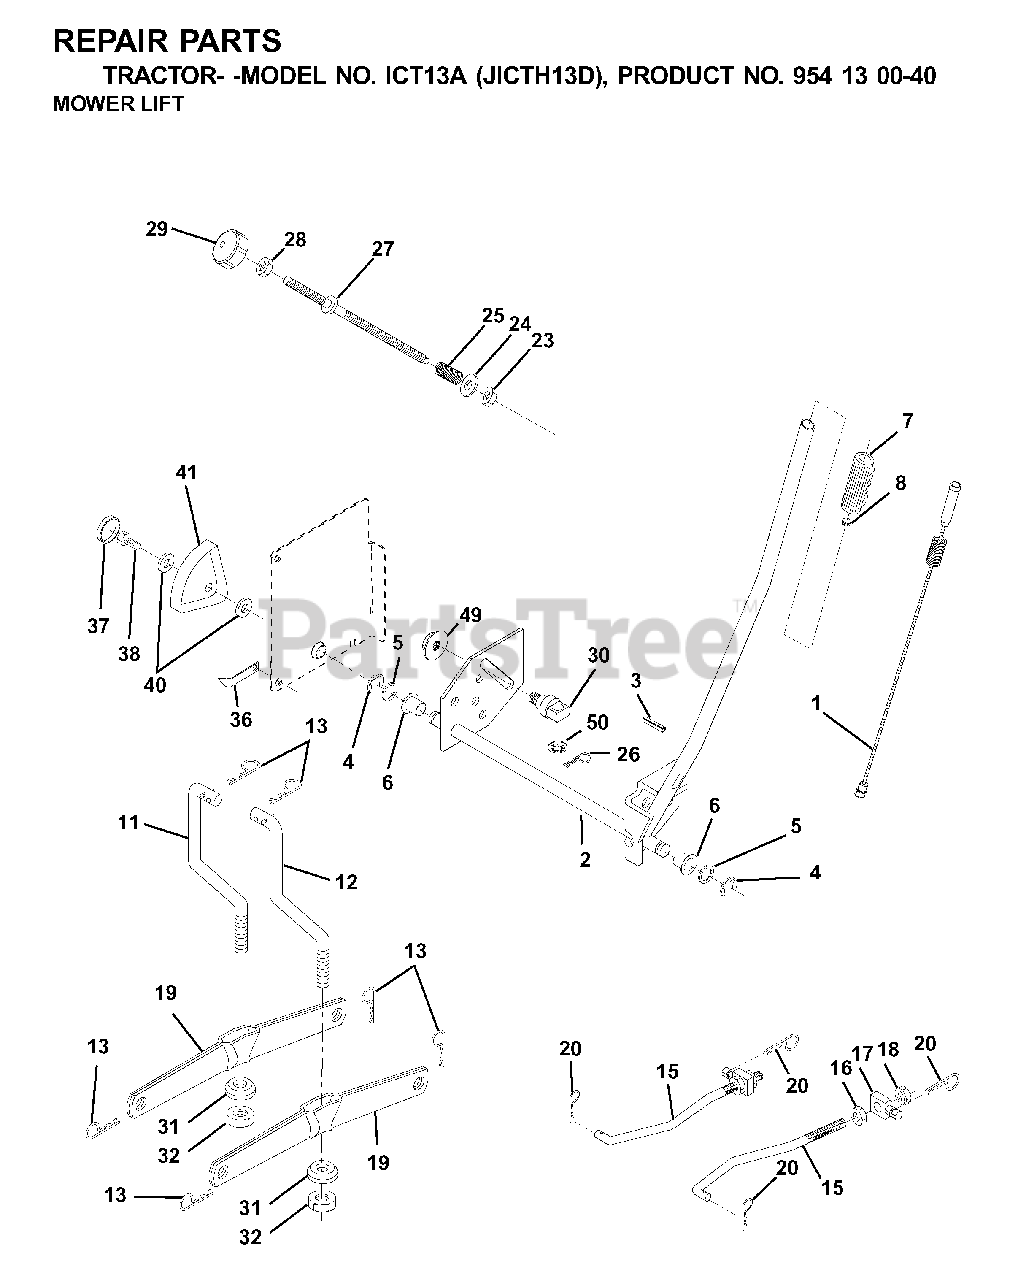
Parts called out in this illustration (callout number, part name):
1	WIRE ASM INNER W/ PLUNGER LT
2	SHAFT ASM R HANDLE
3	PIN GROOVE
4	RETAINING RING LT
6	BEARING.NYLON
7	GRIP HANDLE
8	PLUNGER BUT KIT
11	LINK
12	LINK
13	RETAINER-SPRNG RB
15	LINK.SUSPENSION.FRONT
16	NUT
17	TRUNION
18	NUT
19	ARM.REAR.SUSPENSION
20	SPRING RETAINER
25	SPRING**
26	RETAINER CLIP
27	ROD ADJ LIFT
28	NUT
29	KNOB INF 3/8-16
31	BEARING.PIVOT.LIFT
32	NUT CROWNLOCK 3/8-24
36	POINTER, HEIGHT INDICATOR
37	PLUG,HOLE
38	SCREW 5/16-18X1
41	HEIGHT INDICATOR
49	NUT
50	NUT PUSH M
